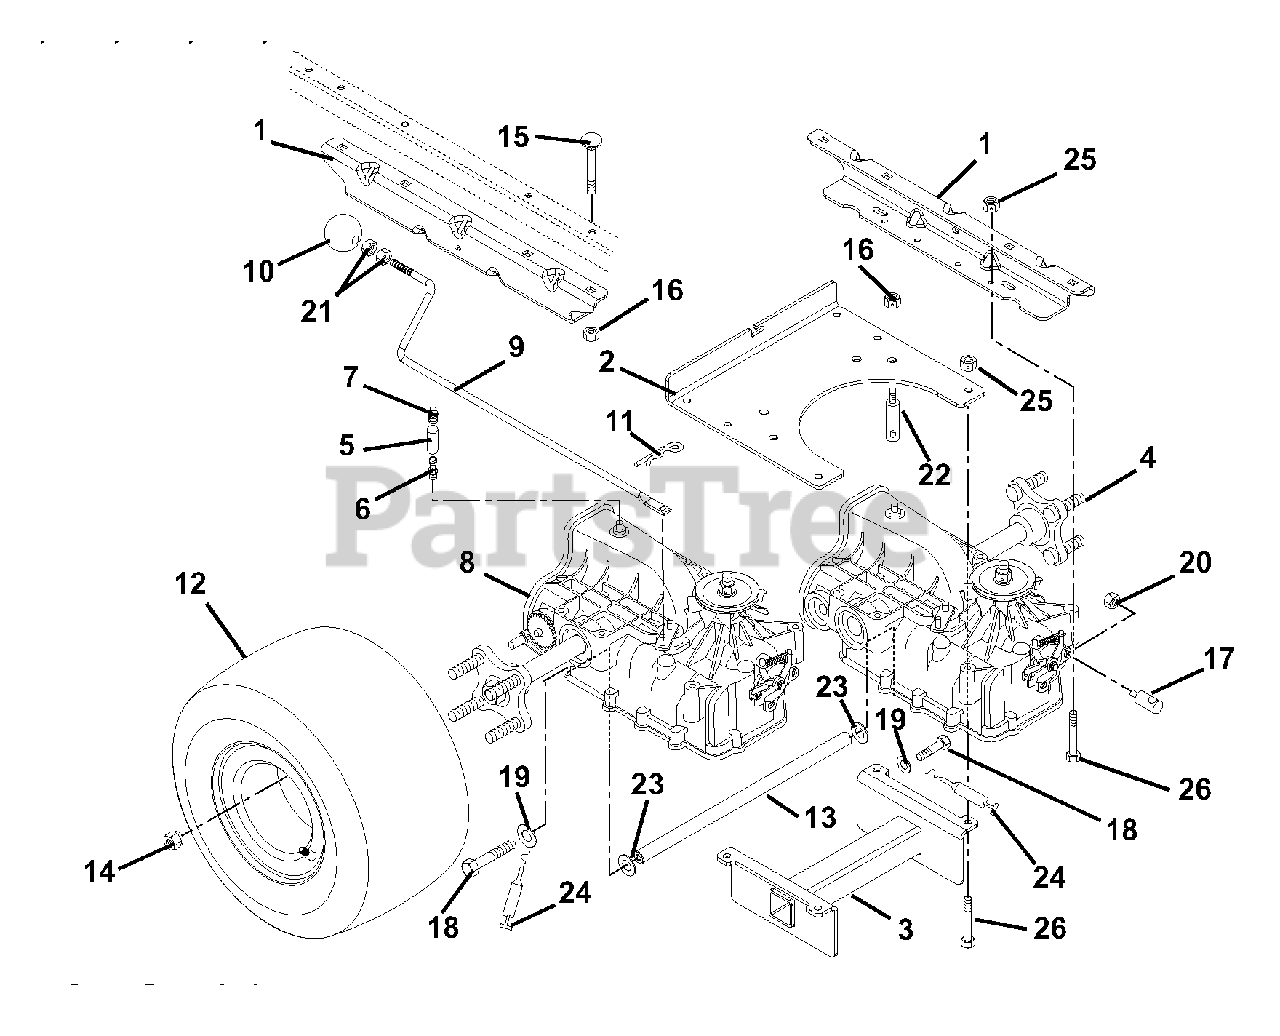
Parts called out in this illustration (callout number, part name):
1	BKT-TRANS AXLE
2	BKT-TRANS AXLE SUPPORT
3	WLDMT-TRANS AXLE BRACE
5	HOSE - VENT
6	FTG-STR .50 O-RING
7	CAP-VENT .50
9	ROD-DUMP IZT
10	KNOB, BALL 5/16-18 X 1.5
11	PIN-HAIR, ENDRIES #25 YWZC
12	ASSY-TIRE 9.5X18-2PLY
12	ASSY-TIRE 8.5X18 2PLY
13	ROD-AXLE BRACE
14	NUT-LUG .50-20 YWZC
15	@BLT-RDHDSQNK .38-16X2.25 G5YZ
16	@NUT-LK-NYL-FLG .38-16 YWZC
17	ROD PIVOT YWZC
18	@BLT-HEX .31-18X2.50 GR5 YWZC
19	@WSHR-LK .31X.078 REG YWZC
20	@NUT-LK-NYL-FLG .31-18 YWZC
21	NUT- JAM .312-18 YWZC
22	SHOULDER STUD
23	WSHR-FL-STL .328X.87X.179 YWZC
24	ADHSV SEALANT (BLUE) 250 ML
25	@NUT-LK-NYL-FLG .31-18 YWZC
26	@BLT-HEX .31-18X2.75 GR5 YWZC
